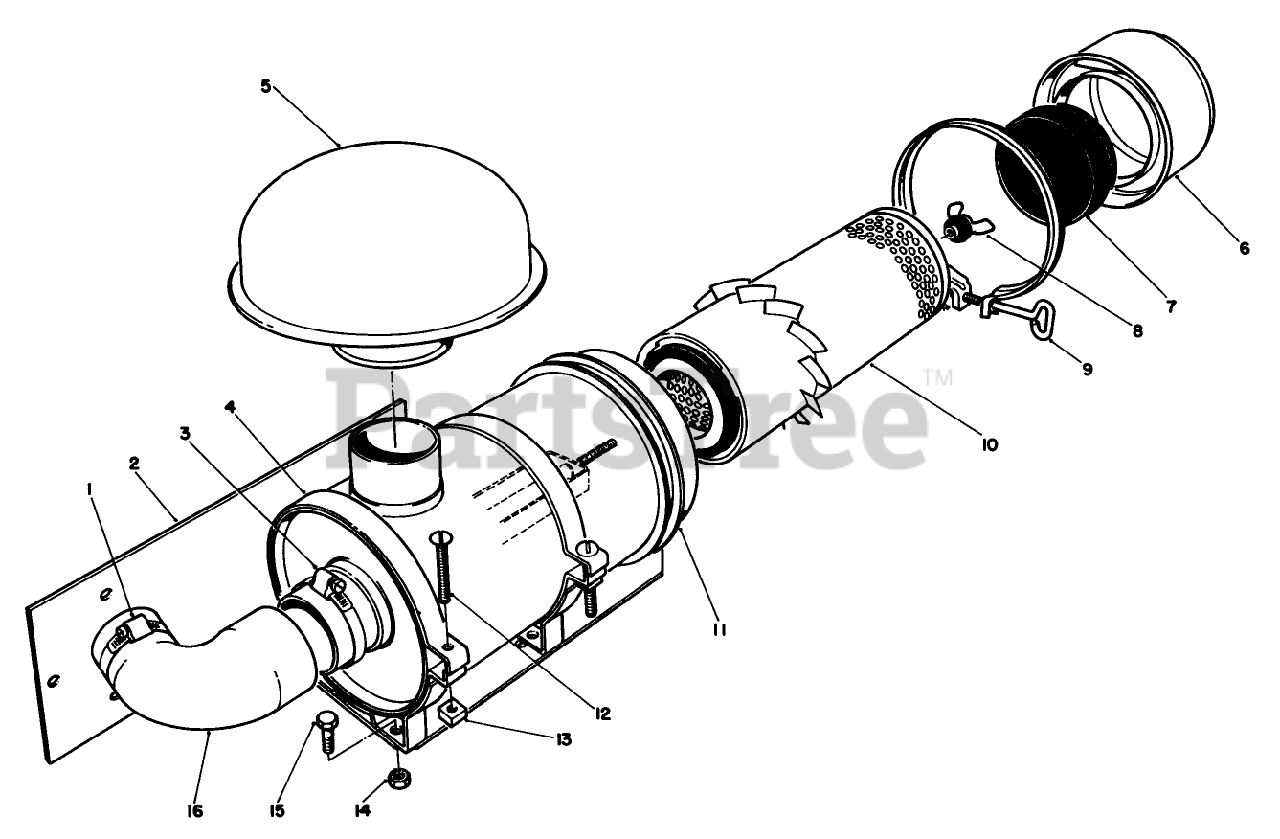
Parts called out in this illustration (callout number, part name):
1	CLAMP-HOSE
2	BRACKET-MOUNTING
3	CLAMP-HOSE
4	MOUNTING BAND ASM
5	HOOD-INLET, AIR
11	Body Assembly
12	SCREW
13	NUT-SQUARE
14	NUT-LOCK, NI
15	SCREW-HH
16	HOSE-REMOTE, AIR CLEANER
